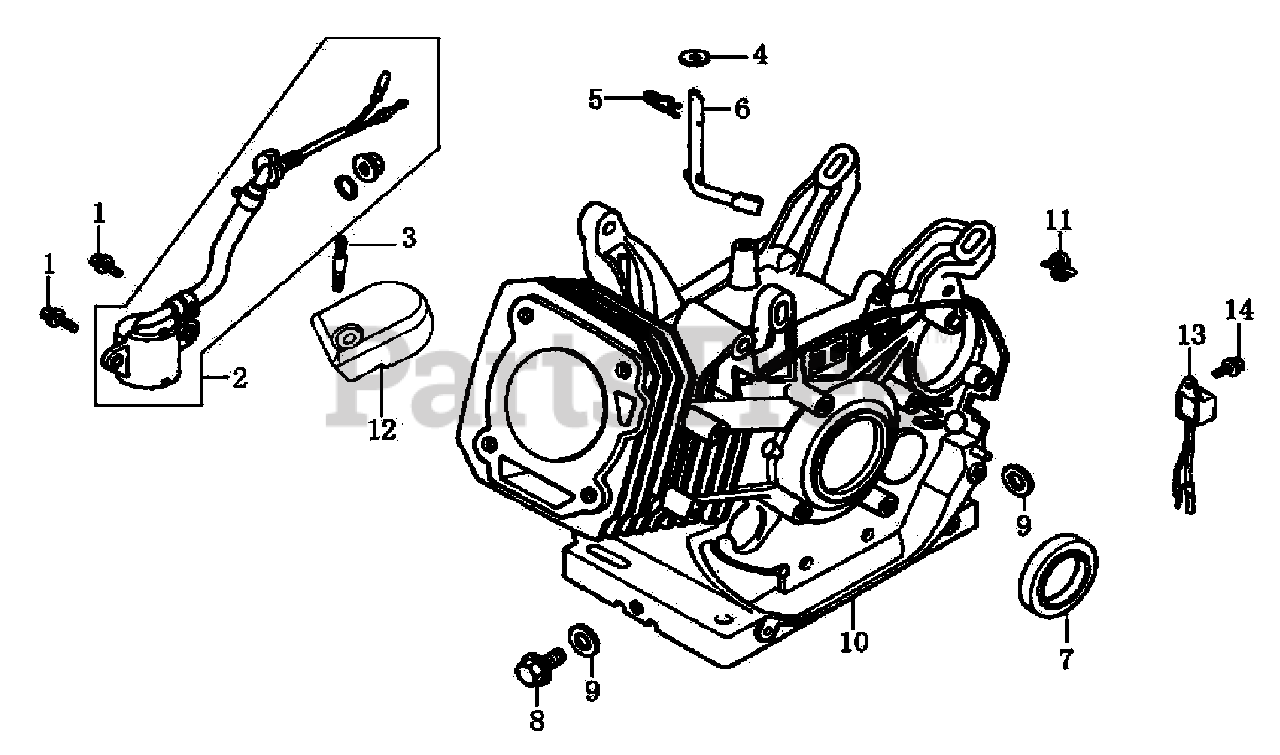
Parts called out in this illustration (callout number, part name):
1	BOLT, FLANGE
2	SWITCH ASSY., OIL LEVEL
3	BOLT, STUD, EXHAUST
4	WASHER, 8*16*1.2
5	PIN, LOCK, 10MM
6	SHAFT, GOVERNOR ARM
7	OIL SEAL 30x46x8
8	BOLT, DRAIN PLUG
9	WASHER, DRAIN PLUG, 12MM
10	CRANKCASE
11	HOLDER, STOP SWITCH
12	COVER, WIRE
13	ALERT UNIT, OIL
14	BOLT, FLANGE, 6x12
